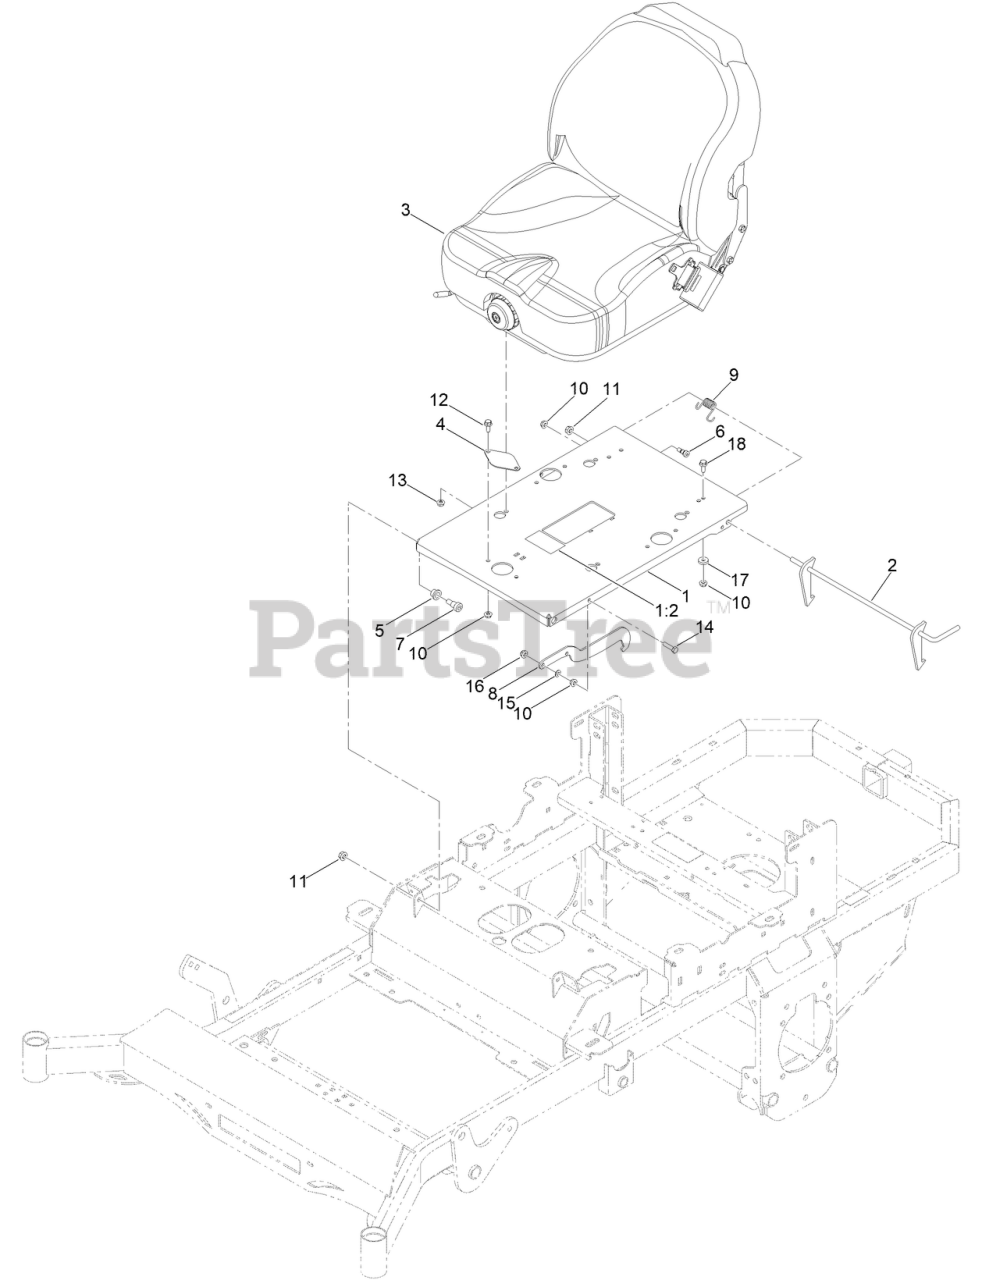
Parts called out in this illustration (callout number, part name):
1	ASM-SEAT PLATEFLOATING W/ DECAL
1:2	DECAL-WARNING, BATTERY
2	MWR SEAT LATCH RELEASE ASSY ABC
3	KGZ-XD FULL SUSP SEAT
4	UNIV FLOATING SEAT COVER PLATE BLACK
5	1/2IN ID X 5/8IN OD X 1/2IN FLANGE BUSH
6	SCREW-HSH
7	1/2 X 1/2 SOCKET SHOULDER BOLT ZC YELLOW
8	MWR SEAT LATCH HOOK BLACK
9	MWR SEAT LATCH SPRING
12	SCREW-HHF
13	5/16-18 NYLON INSERT FLANGE L/NUT ZC
14	SCREW-HH
15	.312IDX.625ODX.062 THK THRUST BRG OI BRZ
16	NUT-HF, NI
17	.312 ID X .875OD X .1875 THK F/W NYL
18	5/16-18 X 3/4 HEX FLANGE BOLT GR 8 YZ
